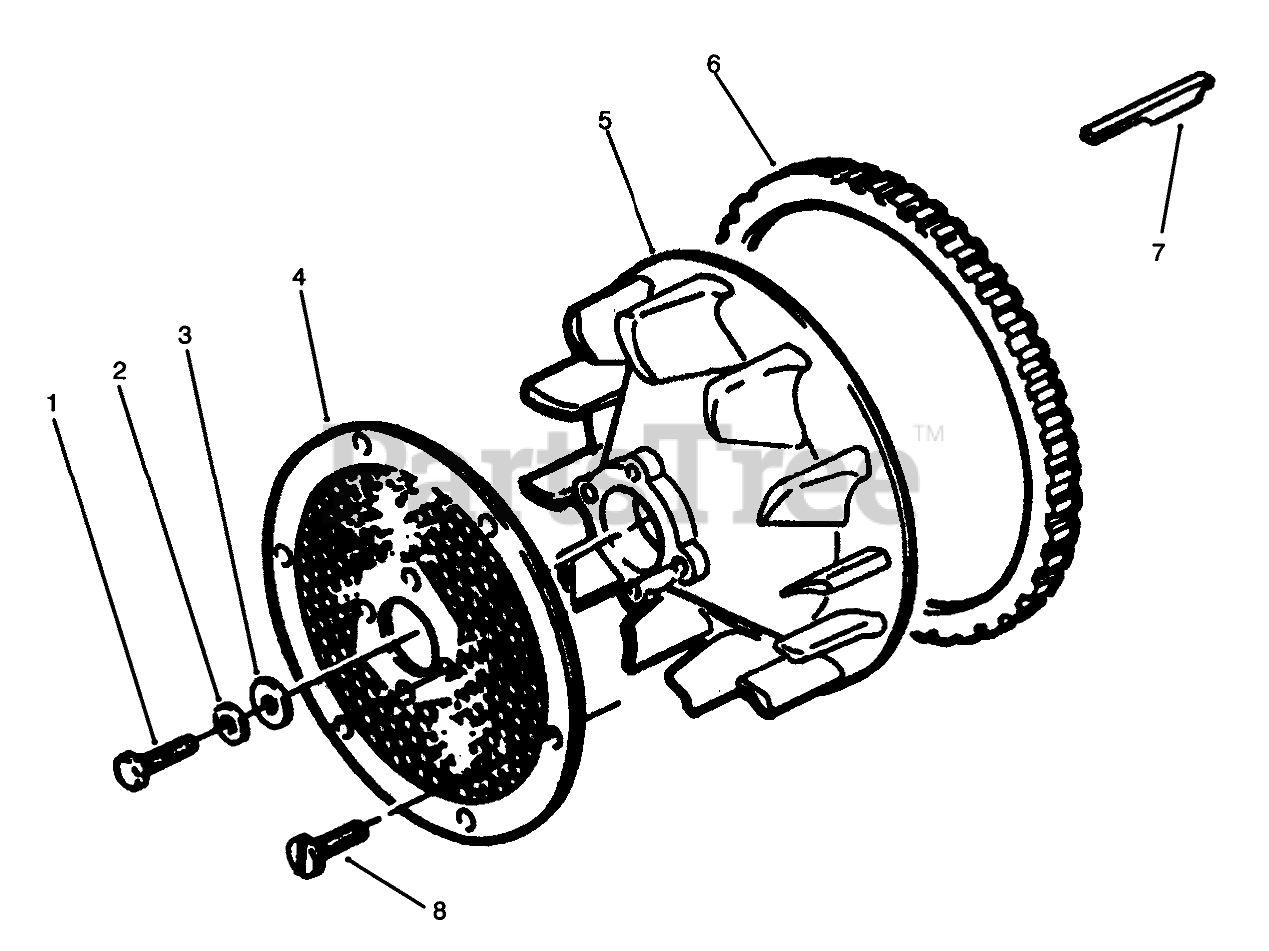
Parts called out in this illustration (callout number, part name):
1	SCREW
2	WASHER-FLAT
3	WASHER-FLAT
4	Screen
5	Flywheel (Incl. Ref. #6)
7	KEY-FLYWHEEL
8	LOCK SCREW
